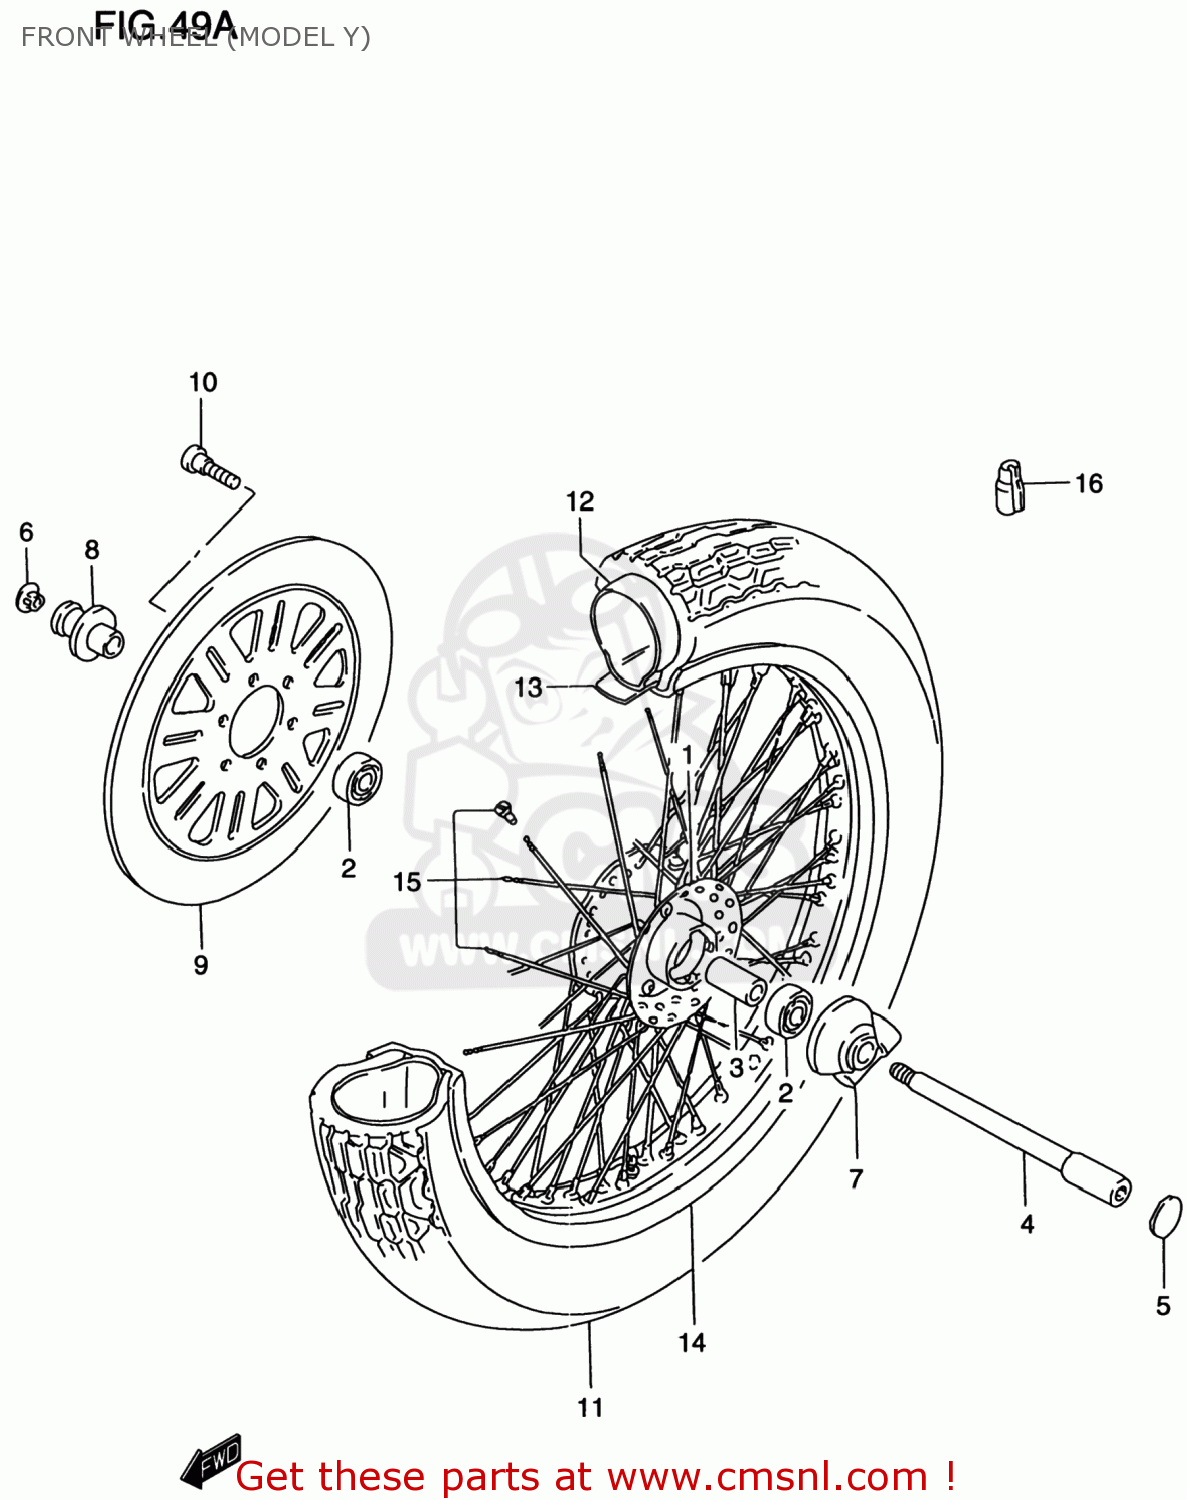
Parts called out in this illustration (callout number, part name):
1	HUB ASSY,FR
2	BEARING
3	SPACER(15.3X21.7X65)
4	AXLE,FR
5	CAP,FR AXLE
6	CAP,FR AXLE
7	BOX ASSY,SPEEDOMETER GEAR
8	SPACER,FR AXLE
9	DISC,FR BRAKE
10	BOLT 8X33
11	TIRE,FR(100/90-19 57H)
12	TUBE
13	PROTECTOR,WHL INR TUBE
14	RIM,FR WHEEL(19X2.15 AL)
15	SPOKE SET,FR WHEEL
16	BALANCER,WHEEL
